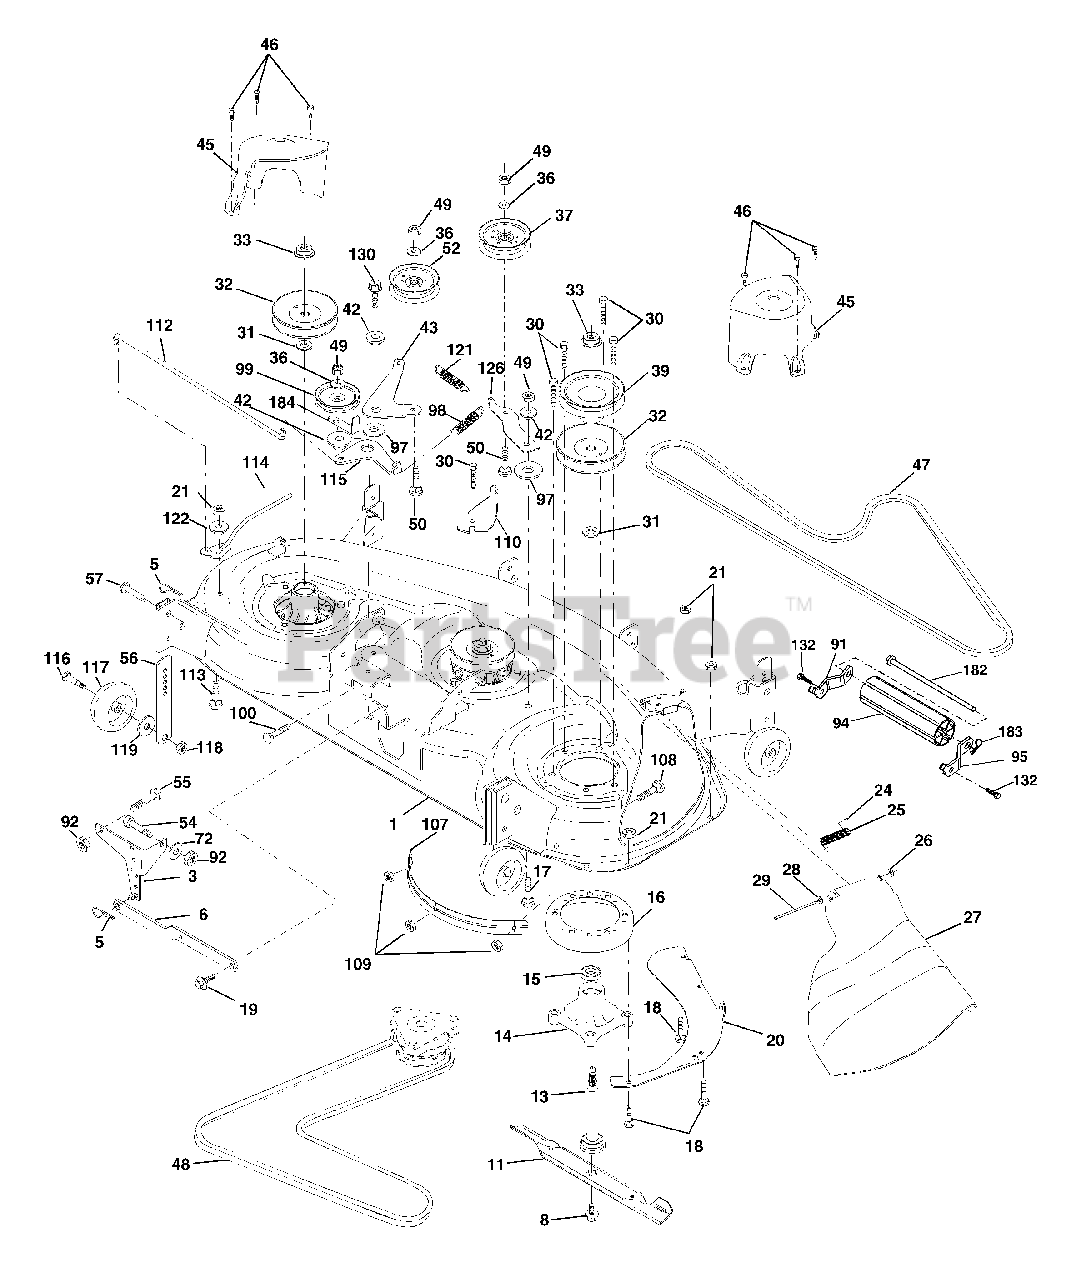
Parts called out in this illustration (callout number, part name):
1	Deck Weldment Mower 48
3	Bracket Asm., Sway Bar
5	Retainer Spring
6	Arm, Suspension, Rear Sway Bar Deck
8	Bolt 7/16 Asm. Blade
11	Blade
13	Shaft Asm. w/Lower Bearing
14	Mandrel Asm. Housing
15	Bearing, Ball, Mandrel
16	Stripper Mandrel Deck
17	Bolt RDHD Sq Neck 3/8-16 x 1.25
18	Bolt, Carriage 5/16-18 x 5/8
19	Bolt, Hex Hd, Shoulder 5/16-18
20	Baffle, Vortex Mower
21	Nut, Crownlock 5/16-18 UNC
24	Cap, Sleeve
25	Spring, Torsion
26	Nut, Push
27	Deflector Shield
28	Washer 11/32 x 5/8 x 16 Ga.
29	Rod, Hinge
30	Screw, Thdroll Washer Head
31	Washer, Spacer Mower Vented
32	Pulley, Mandrel
33	Nut, Flg. Top Lock Cntr. 9/16
36	Washer 13/32 x 13/16 x 16 Ga.
37	Pulley, Idler, Flat
39	Pulley, Idler, Driven
42	Spacer, Retainer
43	Arm, Idler Secondary
45	Cover, Mandrel Deck
46	Screw, Thdroll. 1/4-20 x 5/8
47	V-Belt, Mower, Secondary
48	V-Belt, Mower, Primary
49	Nut, Crownlock 3/8-16 UNC
50	Bolt, Carr. 3/8-16 x 1-1/2 Gr. 5
52	Pulley Idler Flat
54	Bolt Fin Hex 3/8-16 x 1
55	Bolt Carriage Sqnk. 3/8-16 x 1
56	Bar Pnt Adj.
57	Pin Head Rivet
72	Washer 13/32 x 13/16 x 12 Ga.
91	Bracket, Asm Noseroller, LH
92	Nut Lock Hex 3/8-16
94	Noseroller
95	Bracket, Asm Noseroller RH
97	Washer Hardened
98	Spring Primary Drive
99	Pulley Idler "V"
100	Bolt RDHD Sqnk 3/8-16 UNC x 2
107	Baffle Vac Edge Mower
108	Bolt RDHD Sqnk 1/4-20 x 1/2
109	Nut Crownlock 1/4-20
110	Arm Spring Secondary
112	Link Tension Relief Lever
113	Bolt Carr. 5/16-18 x 1
114	Tension Asm. Relief Lever
115	Arm Spring Tension Relief
116	Bolt, Shoulder
117	Gauge Wheel
118	Nut, Centerlock 3/8-16 UNC
119	Washer 3/8 x 7/8 x 14 Ga.
121	Spring Secondary Drive
122	Bushing Pivot Tension Relief
126	Arm, Idler, Primary Deck
130	Screw 3/8-16 x 1.0
132	Screw 3/8-16 x .75
182	Rod Roller Nose
183	Retainer Spring
184	Keeper Belt Idler
